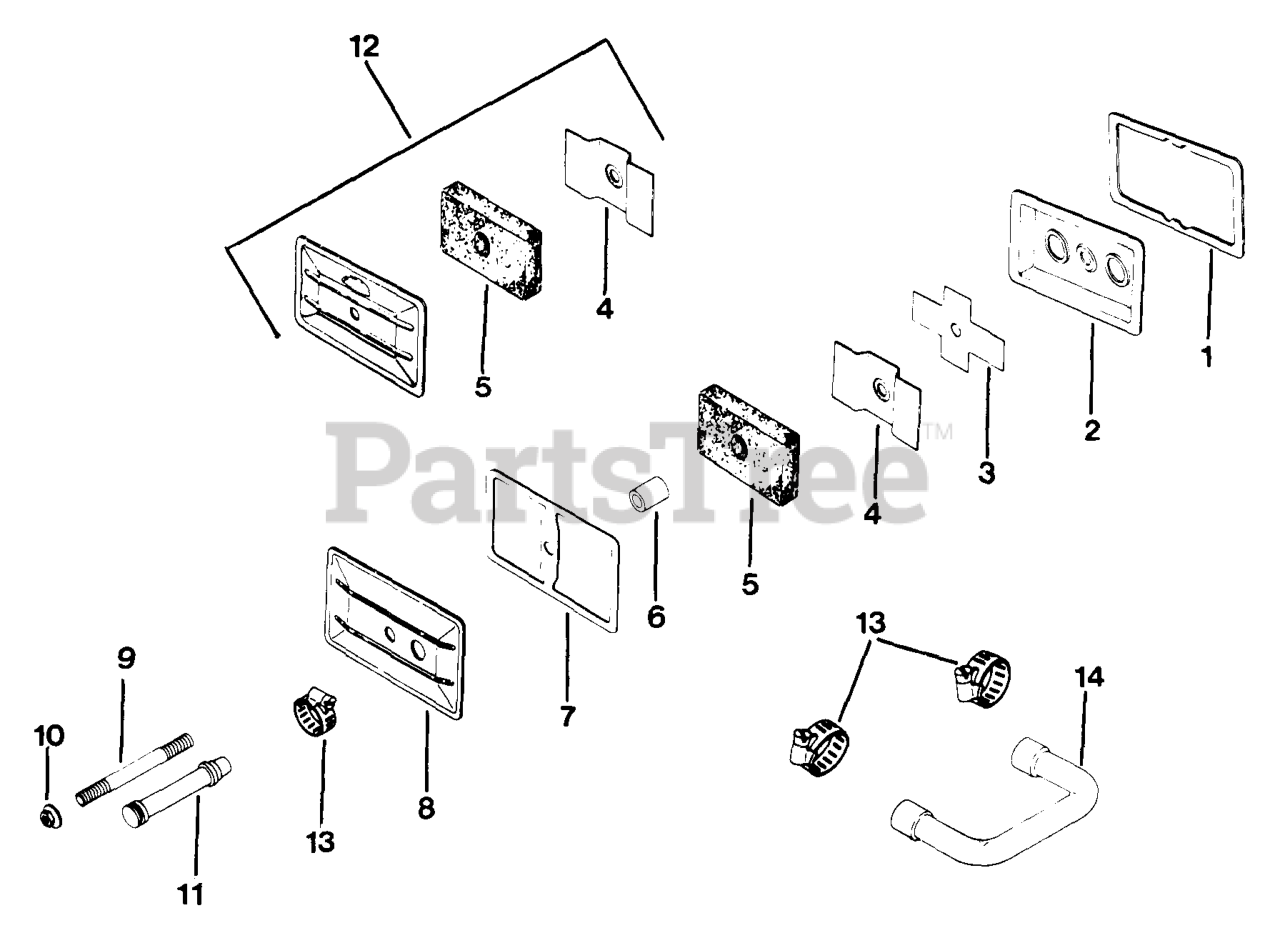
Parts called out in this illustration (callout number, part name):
1	GASKET, VALVE COVER
2	PLATE, BREATHER
3	REED, BREATHER - Use 47 402 01-S Breather Reed
4	BAFFLE, BREATHER
5	FILTER, BREATHER
6	SEAL, BREATHER
7	GASKET, VALVE COVER
8	COVER, VALVE
9	STUD, 1/4-20x3-1/4" - DISCONTINUED
10	PALNUT, 1/4-20
11	HOSE, BREATHER - DISCONTINUED
